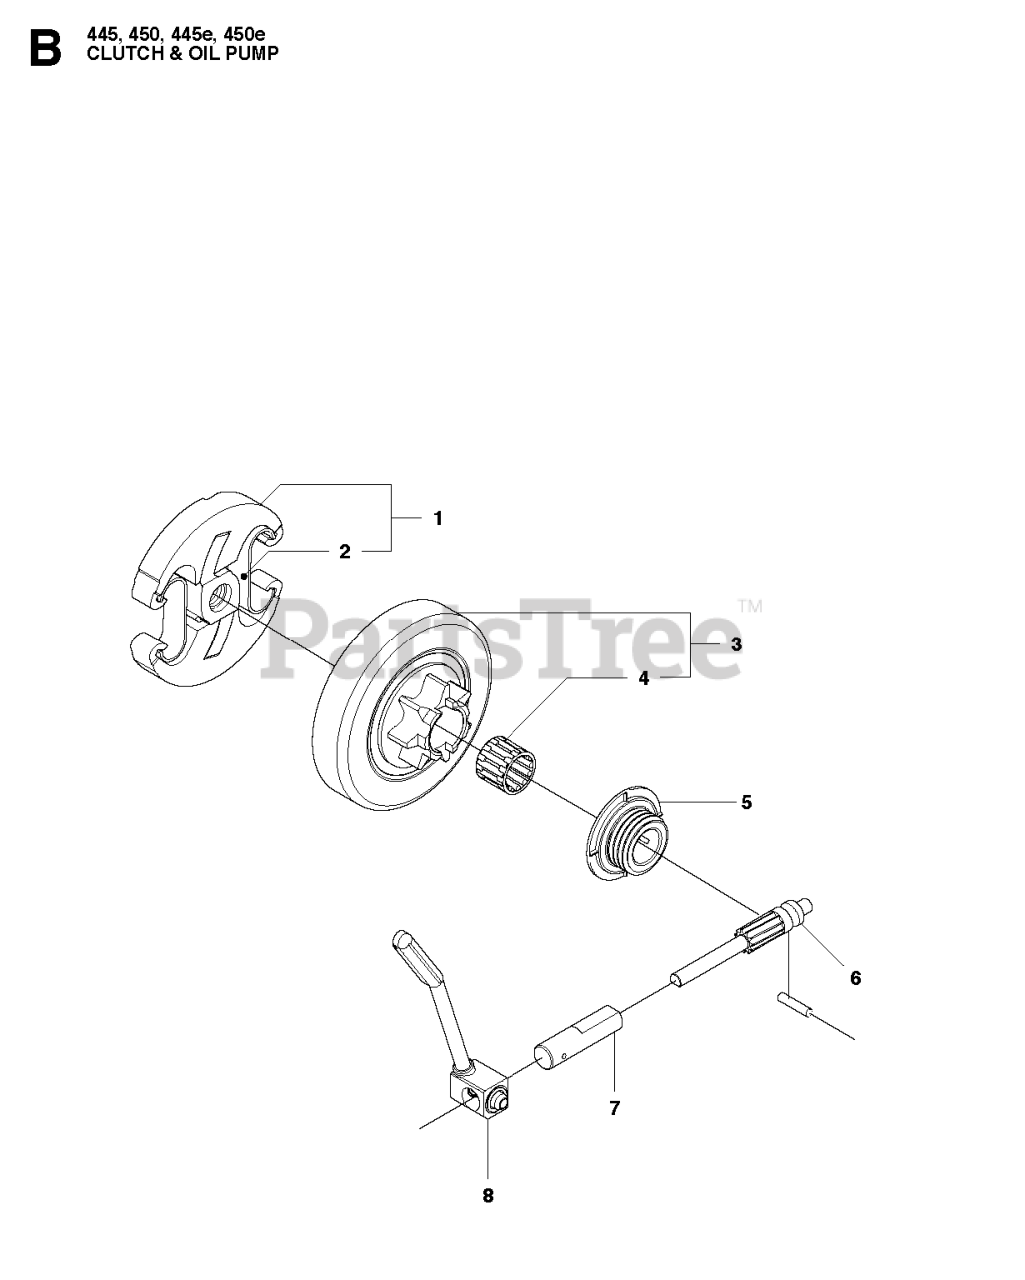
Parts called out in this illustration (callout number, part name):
3	CLUTCH DRUM
4	NEEDLE BEARING
5	GEAR WHEEL OIL PUMP
6	PISTON PUMP
7	PUMP CYLINDER
